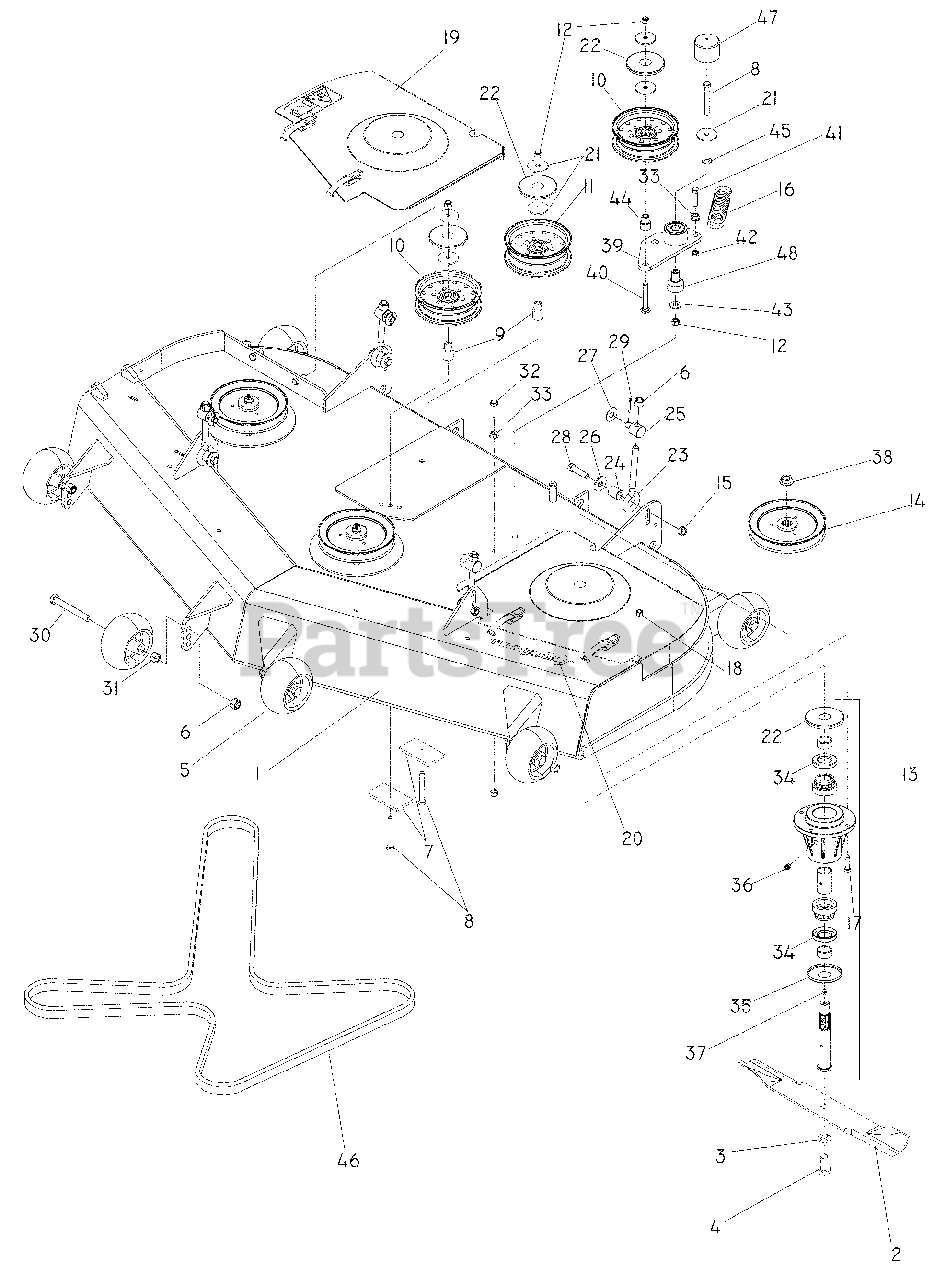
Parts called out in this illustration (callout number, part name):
1	DECK W/DECALS
2	BLADE, 21"
3	WASHER 5/8 SLW
4	HCS 5/8-18 x 1¼
5	WHEEL, GAUGE
6	NUT ½ -13, NYLOC
7	PAD, PAINTED
8	HCS 3/8-16 x 3
9	IDLER BUSHING
10	IDLER PULLEY
11	IDLER PULLEY
12	NUT 3/8-16 HEX NYLOC
13	HOUSING ASM
15	NUT 7/16-14 HEX CTRLK GR A
17	HCS 5/16-18 x 1¼
18	NUT 5/16-18 HEX NYLOC
19	61 BELT SHIELD ASM RT
20	DECAL, TUNNELRAM
21	WASHER - 3/8 SPECIAL
22	TOP DUST CAP
26	SPRING WASHER
27	WASHER, ½ STD FLT
28	HCS 7/16-14 x 1¾
29	PIN COTTER 1/8 x 1
30	HHB ½-13 x 4
31	NUT ½-13 HEX
32	HCS 3/8-16 x 1¼
33	NUT 3/8-16 HEX WHIZLK
34	SHAFT SEAL
35	BOTTOM DUST CAP
36	GREASE POPPET
37	ZERK
38	NUT FLANGE ¾-16
39	ARM, IDLER - W/BEARINGS
40	RHSNB 3/8-16 x 2¾
41	HCS 3/8-16 x 1½ GR 8
42	NUT 3/8-16 HEX JAM
43	WASHER, 3/8 FLAT STD
44	BUSHING, IDLER
45	WASHER, 3/8 SAE FLT
46	DECK BELT
47	CAP, VINYL
48	PIVOT BEARING
